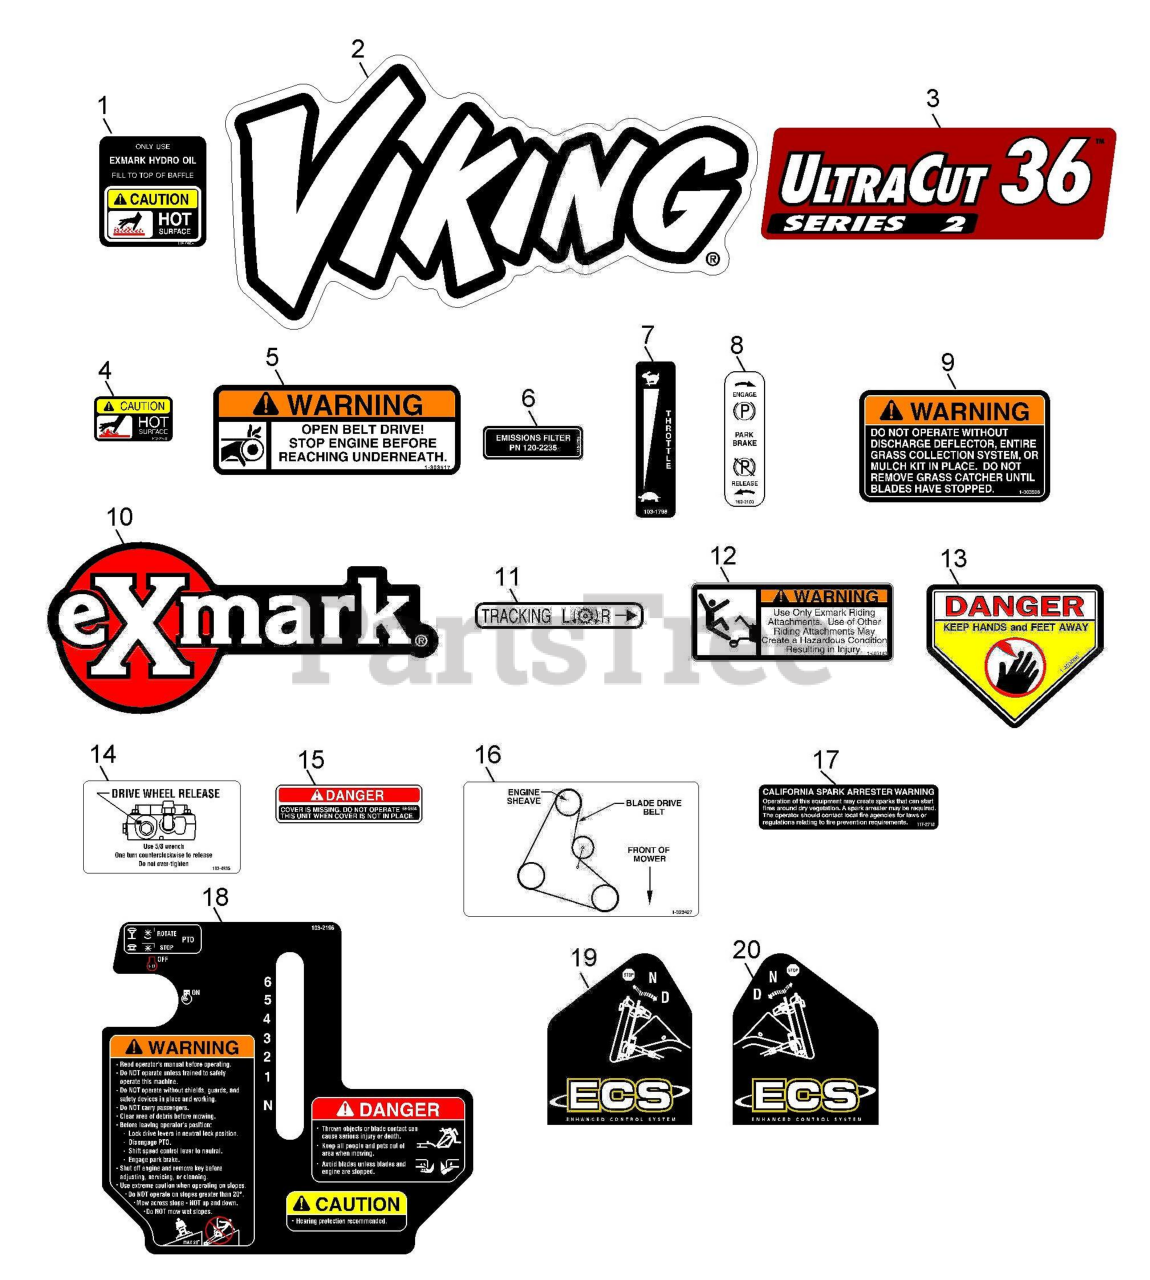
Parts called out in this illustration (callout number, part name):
1	DECAL-HYDRAULIC TANK
2	DECAL,VH MODEL
3	DECAL-ULTRACUT 36 SERIES
4	DECAL-CAUTION
5	DECAL,BELT DRIVE
6	DECAL-FILTER, EMISSIONS
7	DECAL,THROTTLE ONLY
8	DECAL-BRAKE, PARK
9	DECAL-WARNING, DISCHARGE
10	DECAL,EXMARK LOGO
11	DECAL,TRACKING ADJUST
12	DECAL,SULKY WARNING
13	DECAL-DANGER
14	DECAL,DRIVE RELEASE
15	DECAL-COVER, MISSING
16	DECAL,BELT ROUTING 32/36
17	DECAL-ARRESTER, SPARK
18	DECAL,CONSOLE VH ECS
19	DECAL,LH ECS INSTRUCTION
20	DECAL,RH ECS INSTRUCTION
